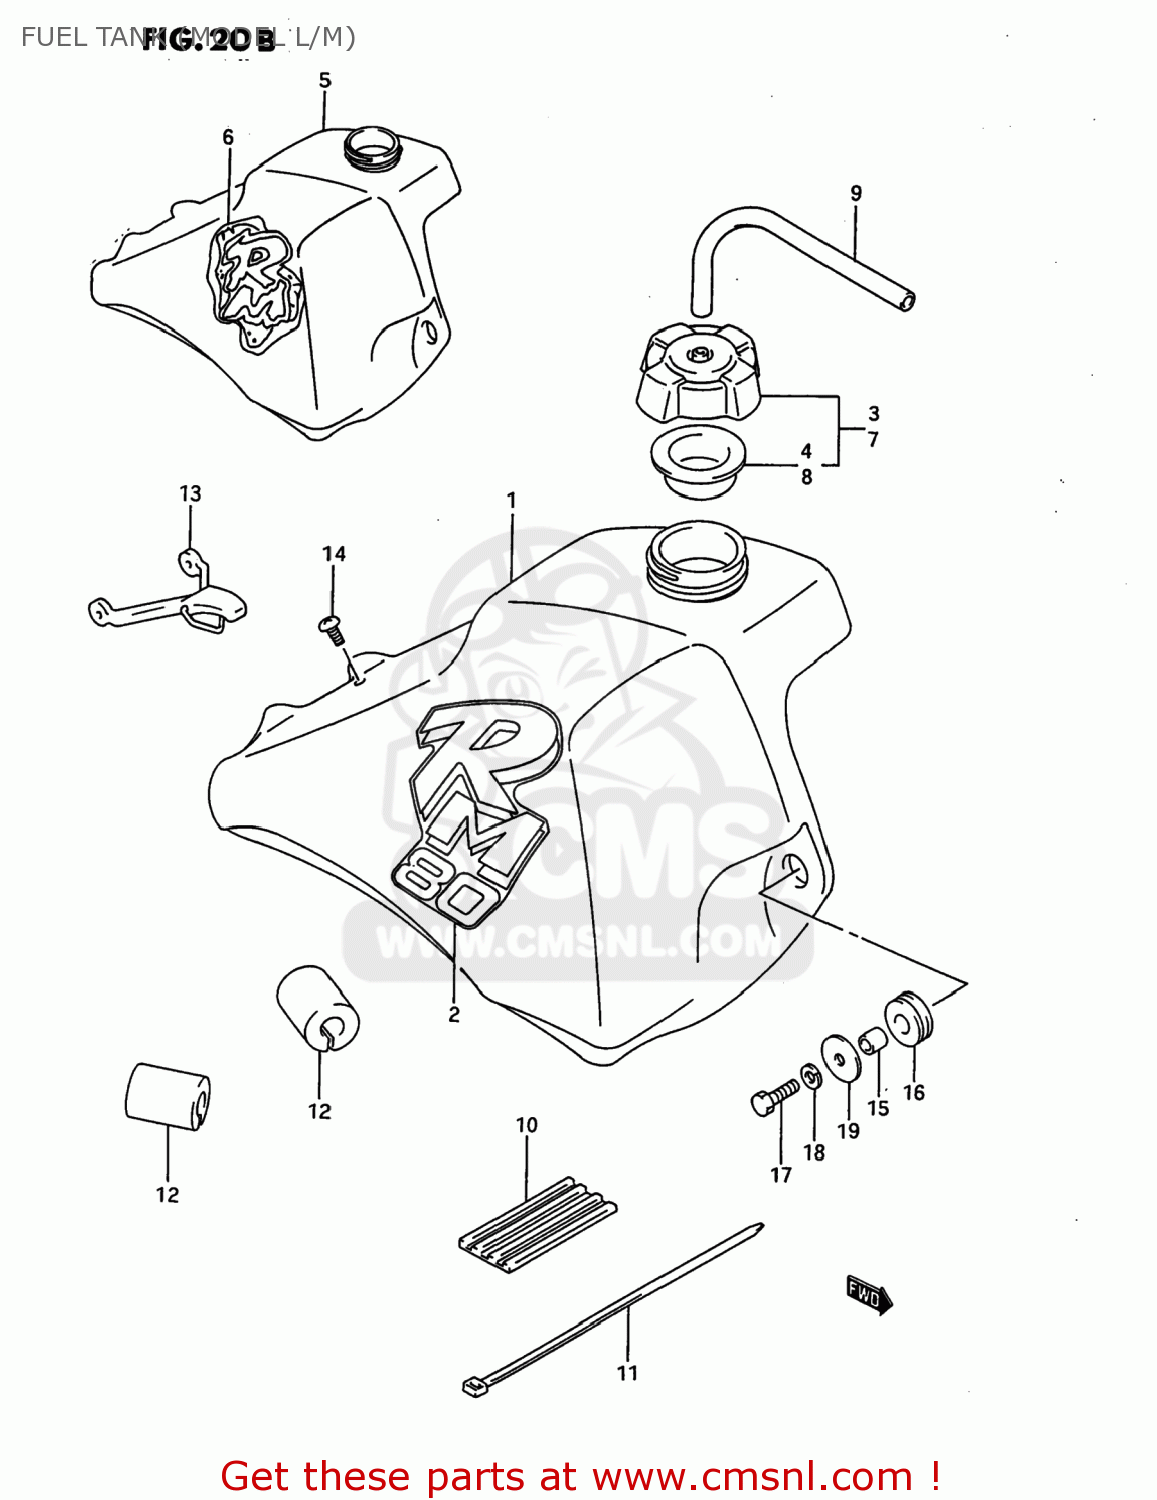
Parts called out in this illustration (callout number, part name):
1	TANK ASSEMBLY,FUEL
2	EMBLEM,FUEL TANK
3	CAP SET,FUEL TANK
4	GASKET,FUEL TANK CAP (NAS)
5	TANK SET,FUEL
6	EMBLEM,FUEL TANK
7	CAP SET,FUEL TANK
8	GASKET,FUEL TANK CAP (NAS)
9	HOSE
10	CUSHION,FUEL TANK UPR FR
11	CLAMP
12	CUSHION,FUEL TANK UPR RR
13	BAND,FUEL TANK RR
14	SCREW
15	SPACER (6.8X10X11.5)
16	CUSHION
17	BOLT
18	WASHER,LOCK
19	WASHER (6.5X24X1.6)
